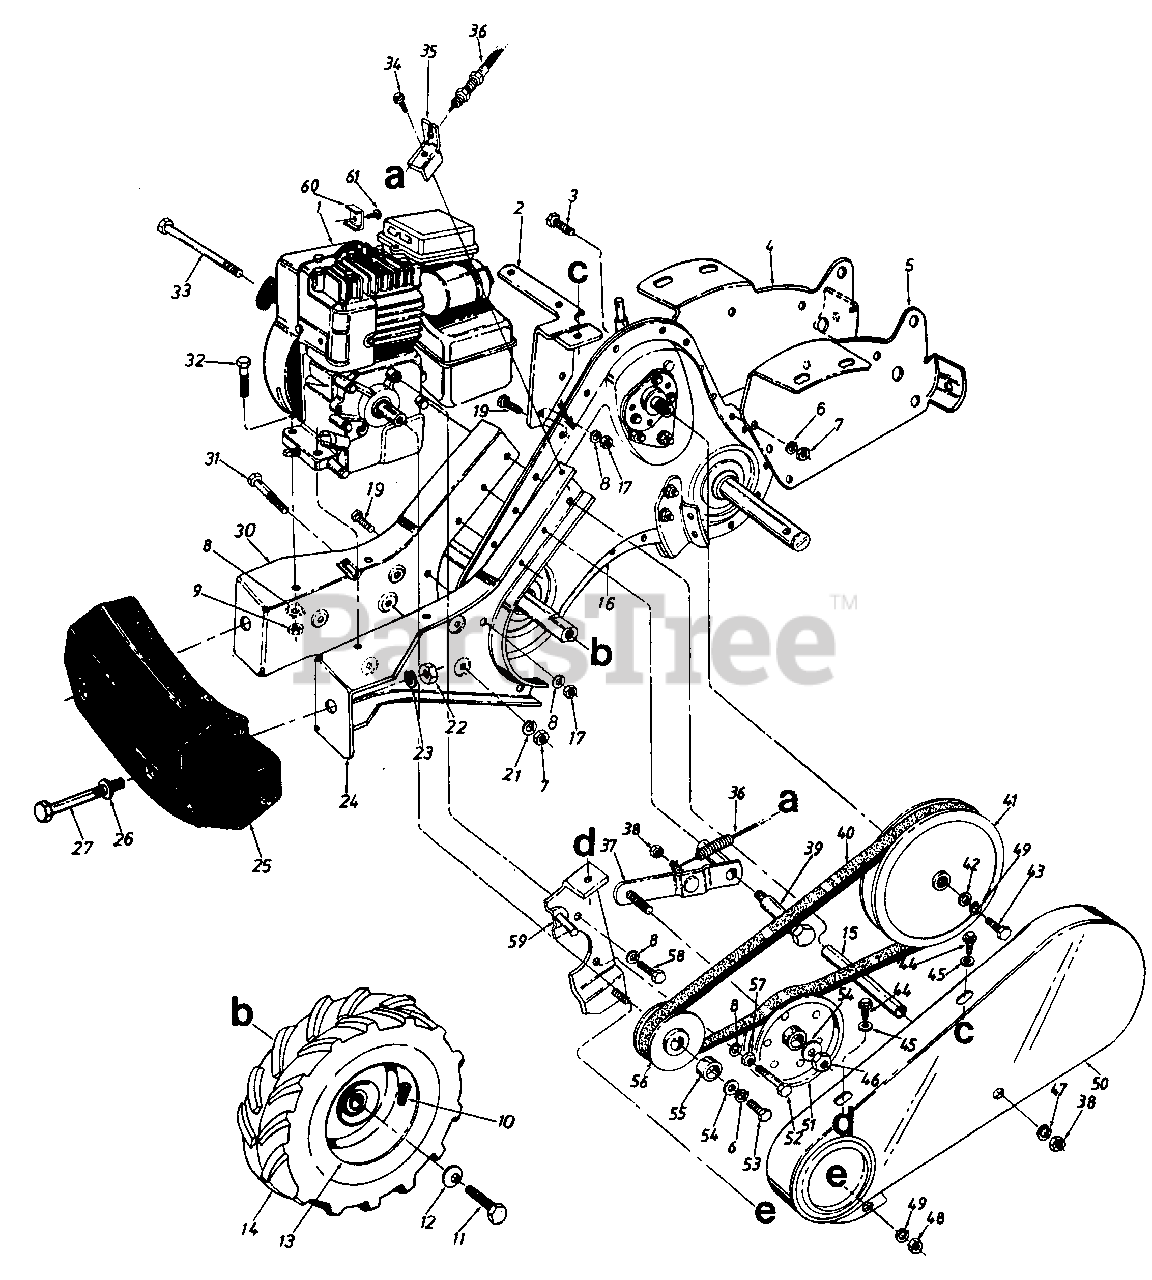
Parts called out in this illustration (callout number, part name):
7	NUT-HEX 3/8-16
8	WASHER-LOCK-5/16
9	NUT-HEX 5/16-18
10	VALVE-TUBELESS AIR
11	SCREW-HEX 5/16-24 X .62
12	WASHER-BELL .337 X .867 X .057
13	WHEEL RIM
14	WHEEL ASSY W/TIRE-LH
16	GEAR CASE ASSY
17	NUT-HEX 5/16-18
19	SCREW-HEX 5/16-18 X .75
21	WASHER-HDL 3/8
22	NUT-HEX 1/2-13
23	WASHER-LOCK-1/2
26	WASHER-FL
27	BOLT-HEX 1/2-13X5.0
32	SCREW-HEX 5/16-18 X 1.50
33	SCREW-HEX
34	SCREW-HEX WASH HD 5/16-18
36	CABLE-CLUTCH CONTROL
39	SCREW-SHLD
40	BELT-V 1/2 X 57.0
42	WASHER-FL
43	SCREW-HEX 1/4-28 X .75
44	SCREW-HEX WASH SF TAPP
45	WASHER-FL
46	NUT-HEX CENTER JAM 3/8-24
47	WASHER-FL-.344 ID X 1.12 OD X .063
48	NUT-HEX 1/4-20
49	LOCK WASHER 1/4 DIA
51	PULLEY-IDLER
52	SCREW-HEX 5/16-24 X 1.75
53	BOLT-3/8 NF X 1"GR5
54	WASHER-FL-.385 X 1.00 X .135
56	PULLEY HALF-ENGINE
57	NUT-5/16-24
58	SCREW-HEX 5/16-24 X .62
61	SCREW-HEX SEMS #10-32
